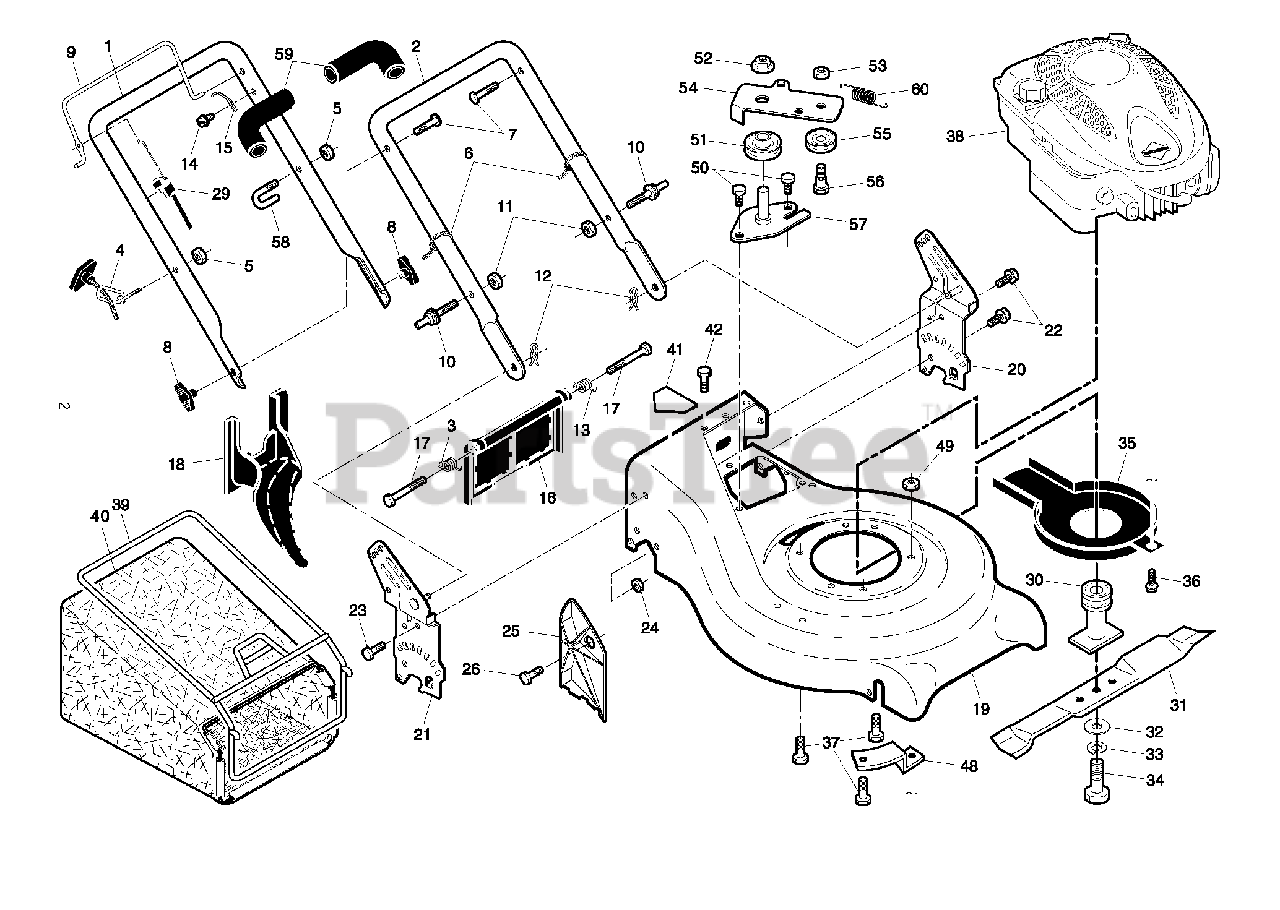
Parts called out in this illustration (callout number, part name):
2	HANDLE LOWER
3	SPRING.RH.REAR.DOOR.21.RWGD
4	GUIDE.ROPE.STD.BLK.ZIN
5	NUT
6	TIE GUIDE
7	BOLT, HANDLE 5/16-18X1.75
8	KNOB, DEFLECTOR
11	NUT.CENTERLOCK.5/16-
12	HAIRPIN COTTER
13	SPRING.LH.REAR.DOOR.21.RWGD
15	BRACKET UPSTOP
16	REAR DOOR ASSEMBLY
18	PLUG.MULCHER.RGD.21.
20	BRKT.ASM HNDL
21	BRKT.ASM.HNDL
22	SELF-TAPPING SCREW 5/16-18X3/4
23	BOLT, HEX HEAD 5/16-18
24	NUT.71038.31-18.HEX.NYLOCK
25	CLIPPING DEFLECTOR
29	SNAP-ON.ZONE.CABLE.ASS
30	BLADE ADAPTOR / PULLEY
31	BLADE.21.PUSH
32	WASHER,HARDEN
33	LOCKWASHER
34	SCREW, HEX HD 3/8-24 X 1-3/8
35	DEBRIS SHEILD
36	SCREW.HEX.WSH
37	BOLT 3/8-16X1-1/8
39	FRAME, GRASSBAG
41	DECAL.INTERNATIONL.CUTFINGER
48	BRACKET
51	PULLEY.IDLER
52	NUT
54	ARM.IDLER
55	IDLER PULLEY
57	BRACKET.IDLER.ASM.EZ
59	GRIP.HANDLE.FOAM.WIDE.(1 SIDE)
60	SPRING, RETURN
